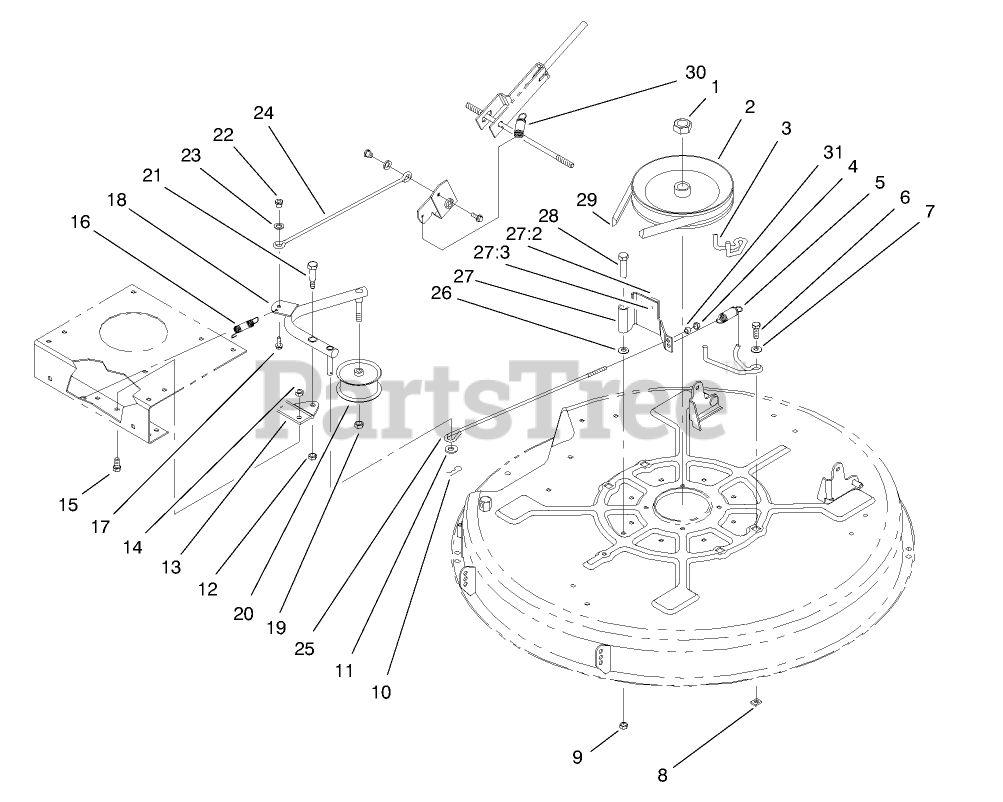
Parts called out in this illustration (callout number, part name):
1	NUT-HEX
2	PULLEY-DECK
3	GUIDE-BELT, DECK
4	NUT-LOCK, NI
5	SPRING-EXTENSION
6	SCREW-HH
7	WASHER-PIVOT
8	NUT-RETAINER
9	NUT-LOCK, NI
11	WASHER-FLAT
12	NUT-LOCK, NI
13	PLATE-MOUNTING, IDLER
14	NUT-LOCK, NI
15	SCREW-HH
16	SPRING-RETURN, BRAKE
17	SCREW-HHF
18	ARM-IDLER WA (BLACK)
19	NUT-LOCK, NI
20	PULLEY-IDLER
21	SCREW-SHOULDER, HH
22	POST-MOUNTING, LINKAGE
23	WASHER-FLAT
24	ROD-ENGAGE, DECK
25	ROD-BRAKE, DECK
26	WASHER-PLAIN
27	BRAKE ARM ASM
27:2	PAD-BRAKE
27:3	RIVET-BLIND
28	BOLT-SHOULDER
29	V-BELT
30	CABLE SPRING ASM
31	BALL-SWIVEL, STOP
